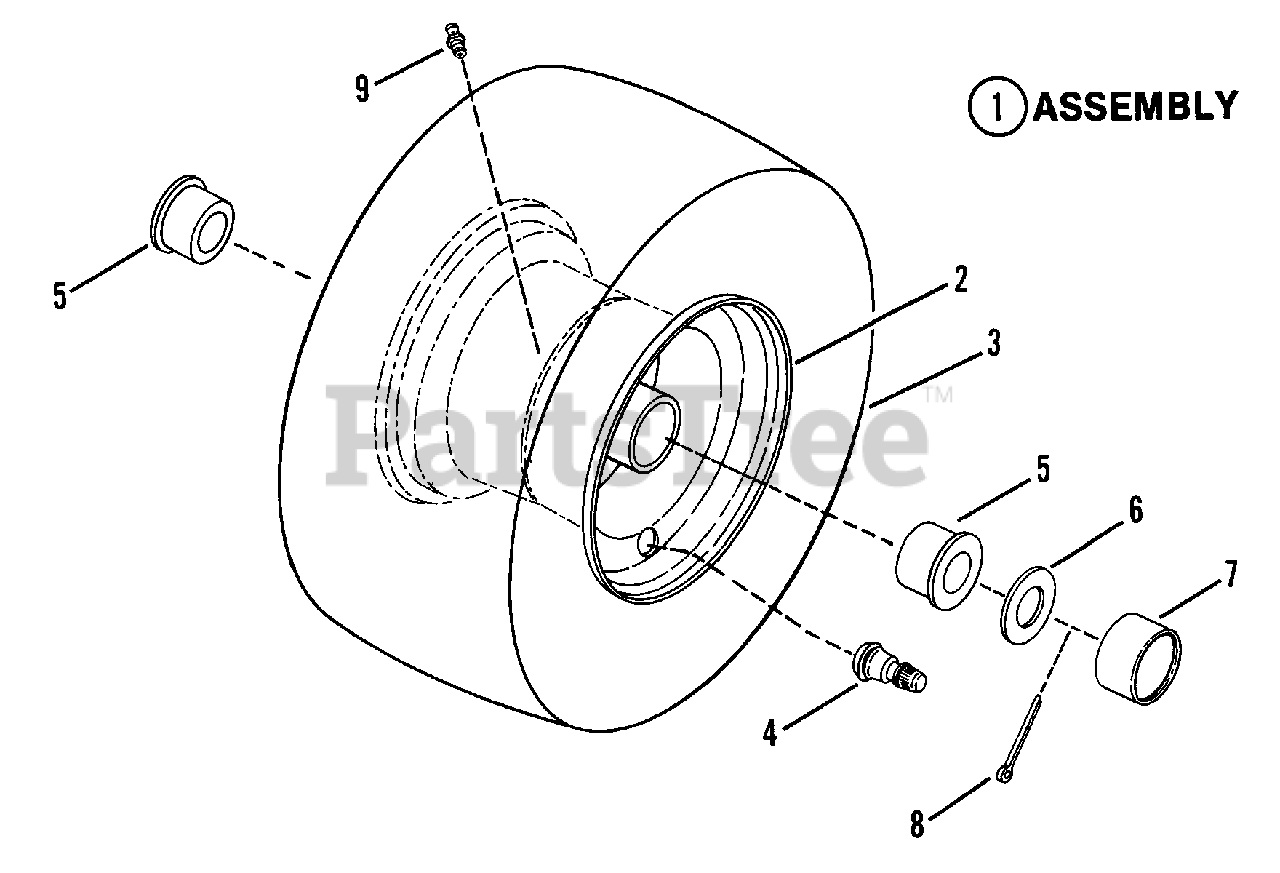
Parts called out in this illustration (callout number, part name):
1	ASSEMBLY, Front Tire & Rim
2	RIM
3	TIRE, 15 x 6.00 x 6
4	VALVE, Air
5	BEARING, Wheel
6	WASHER
7	COVER, Dust
8	COTTER-PIN
9	FITTING, Lube 1/4-28 Tapered Thread
